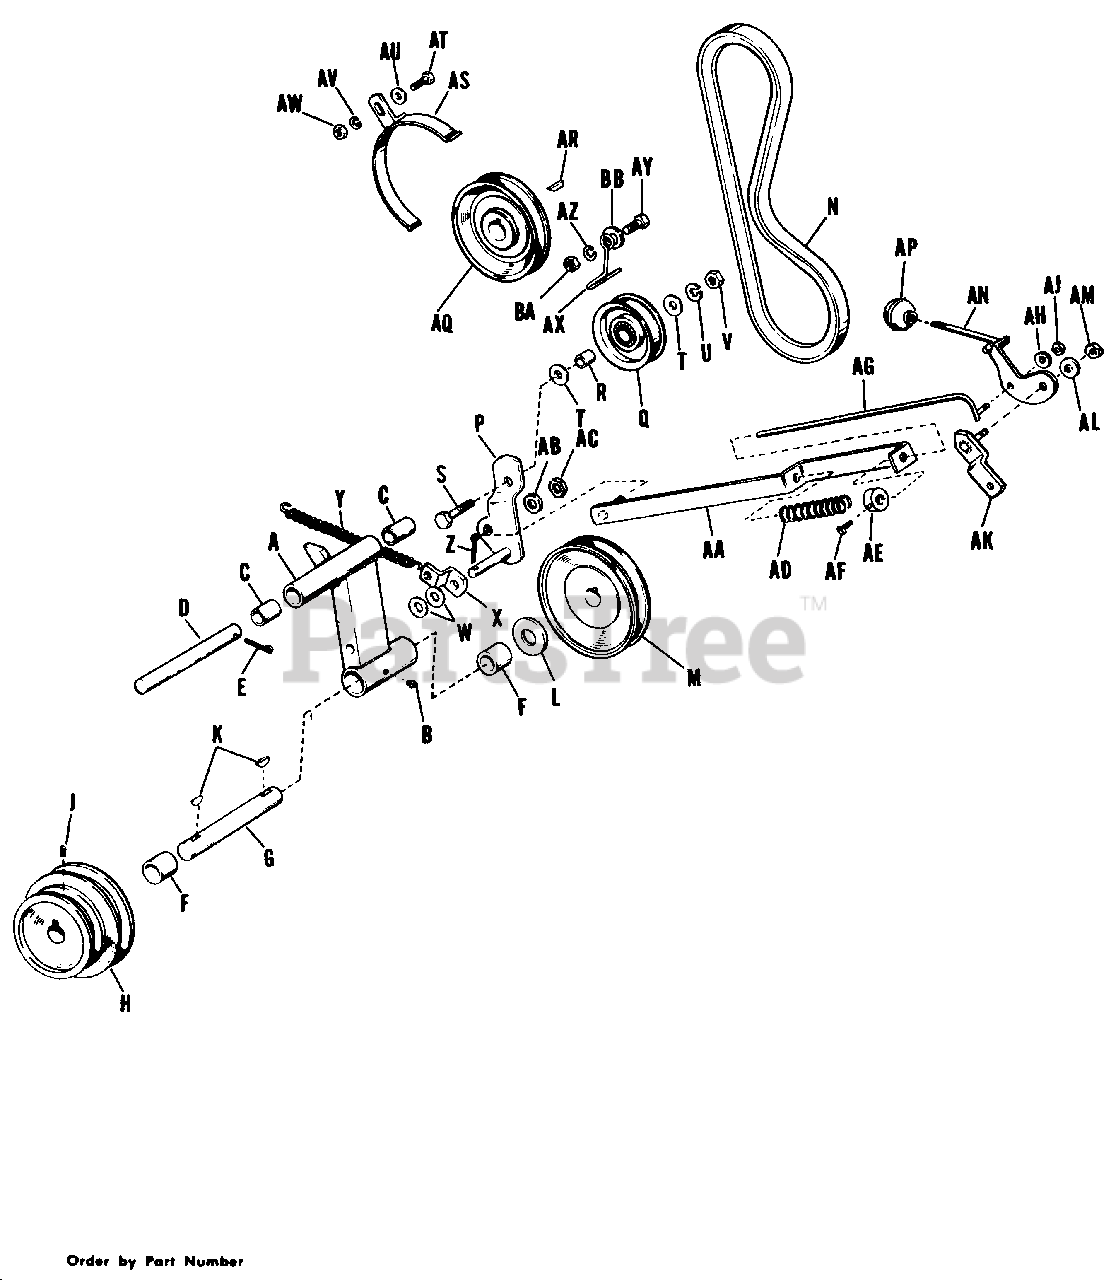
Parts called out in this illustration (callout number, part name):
A	Bracket Assembly, Drive
B	Fitting, Grease
D	Rod, Pivot
E	Pin, Cotter
F	Bearing, Needle
G	Shaft, Power Take-Off
H	Pulley, Power Take-Off
J	Screw, Set, Cup Point, Socket Hd., 5/16"-18 N.C. x 5/16" lg.
K	Key, Woodruff
N	Belt, "V", Power Take-Off
P	Lever Assembly, Idler
Q	Pulley, Idler
S	Capscrew, Hex Hd., 3/8"-16 N.C. x 1-1/4" lg.
T	Washer, Plain, 5/16"
U	Washer, Lock, 3/8"
V	Nut, Hex, Full, 3/8"-16 N.C.
W	Washer, Plain, 3/8"
X	Clip, Spring
Y	Spring, Tension
Z	Pin, Cotter, 1/8" x 3/4" lg.
AA	Guide Assembly, Rod
AB	Washer, Plain, 3/8"
AC	Nut, Lock, Hex Hd., Full, 3/8"-l6 N.C.
AE	Collar, Set
AF	Screw, Set. Sq. Hd. Cup Pt., 1/4"-20 N.C. x 3/8" lg.
AG	Rod Assembly, Clutch
AH	Washer, Plain, 5/16"
AJ	Nut, Lock, Hex Hd., Full, 5/16"-18 N.C.
AK	Pivot Bar Assembly
AL	Washer, Plain, 3/8"
AM	Nut, Lock, Hex Hd. Full, 3/8"-16 N.C.
AN	Lever Assembly, Clutch
AS	Guard Assembly, Belt
AT	Capscrew, 3/8"-16 N.C. x 1" lg.
AU	Washer, Plain, 3/8"
AV	Washer, Lock, 3/8"
AW	Nut, Hex, Full, 3/8"-16 N.C.
AX	Stop, Belt
AY	Capscrew, 3/8"-16 N.C. x 7/8" lg.
AZ	Washer, Lock, 3/8"
BA	Nut, Full, Hex, 3/8"-16 N.C.
BB	Washer, Plain, 3/8"
